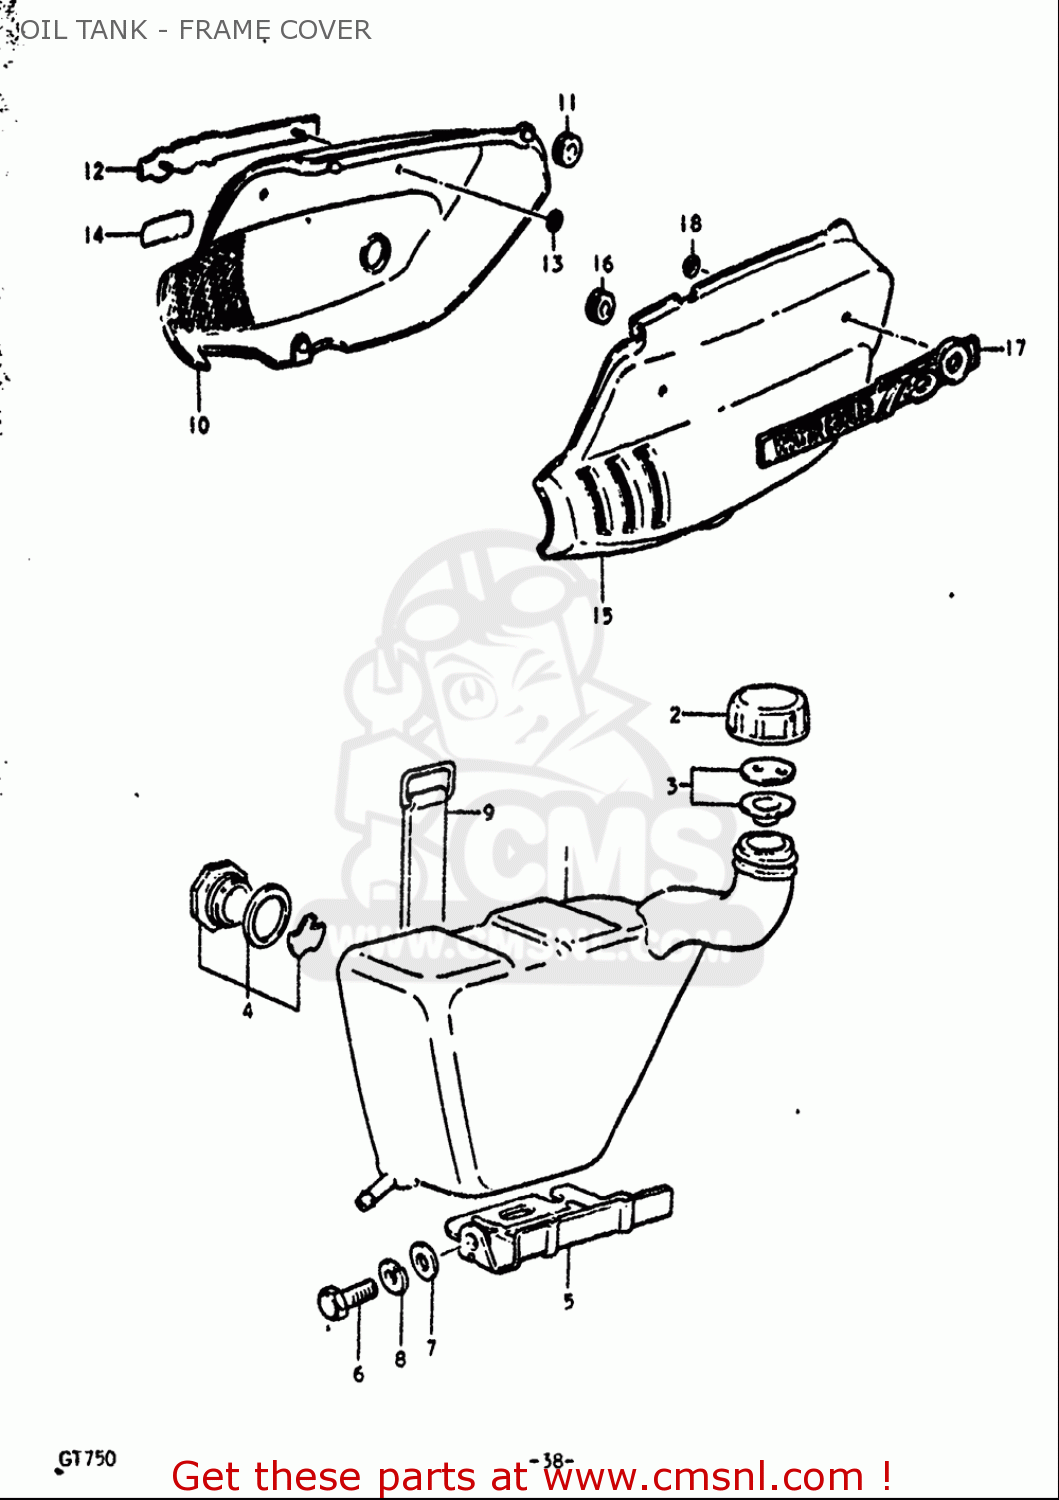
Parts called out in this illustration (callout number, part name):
2	CAP,OIL TANK
3	GASKET SET (NAS)
4	LENS SET,OIL LEVEL
6	BOLT
7	WASHER
8	WASHER,LOCK
9	BAND
10	COVER SET,FRAME,R
11	CUSHION
12	EMBLEM,FRAME COVER,R
13	NUT (4MM)
14	EMBLEM,CCIS
15	COVER SET,FRAME,L
16	CUSHION
17	EMBLEM,FRAME COVER,R
18	NUT (4MM)
